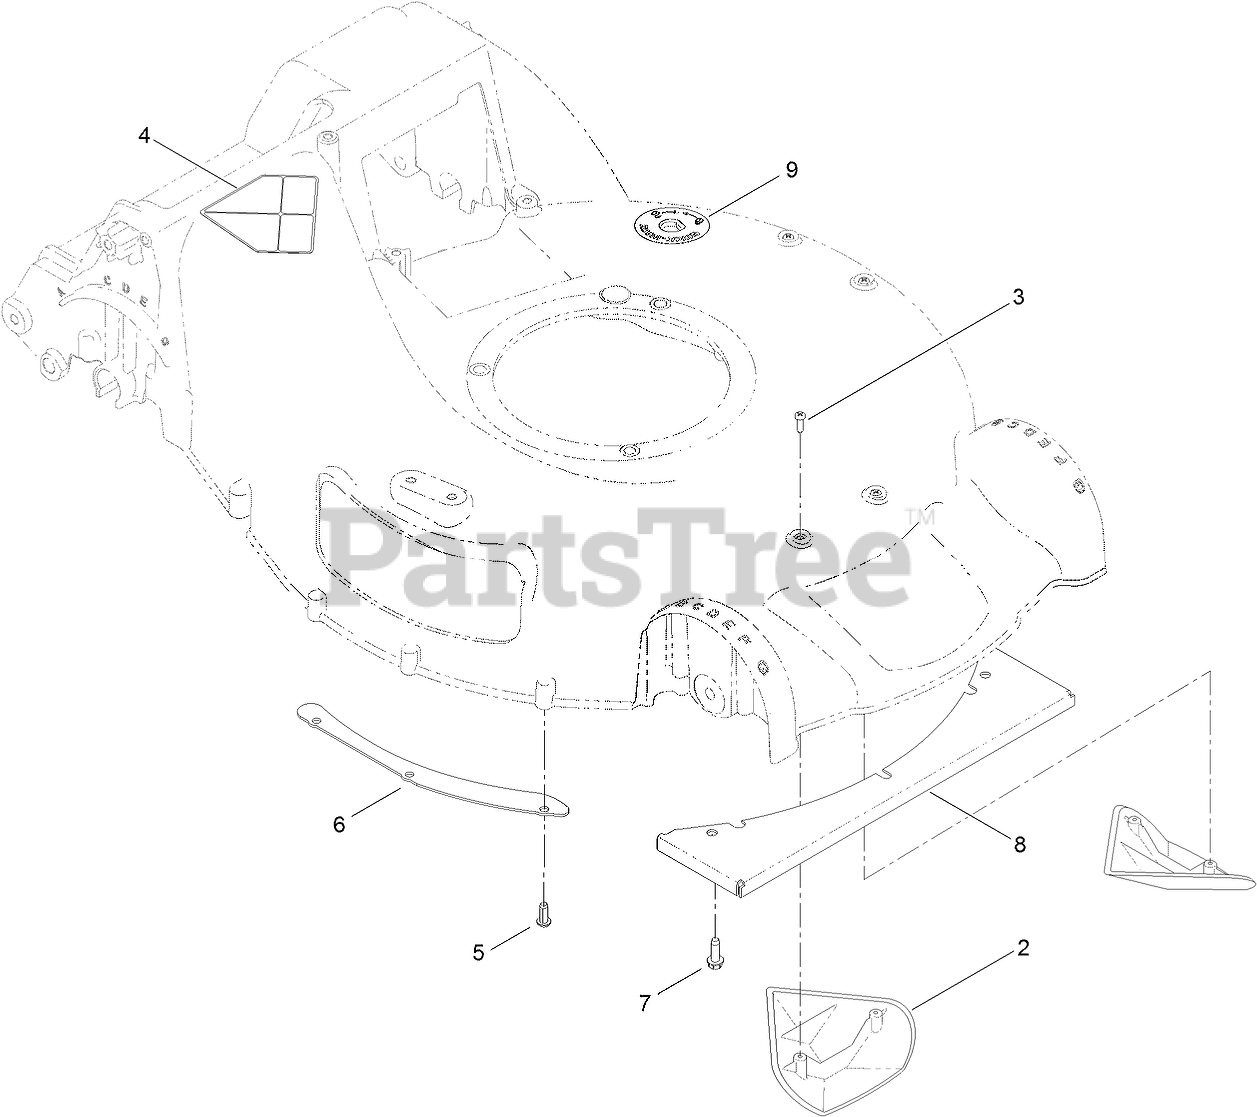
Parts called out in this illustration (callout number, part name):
2	KICKER-HOUSING
3	SCREW-PPH
4	DECAL-DANGER
5	SCREW
6	SHEET-LIP
7	SCREW-HWHTF
8	PLATE-COVER, FRONT
9	DECAL-PORT, WASHOUT
